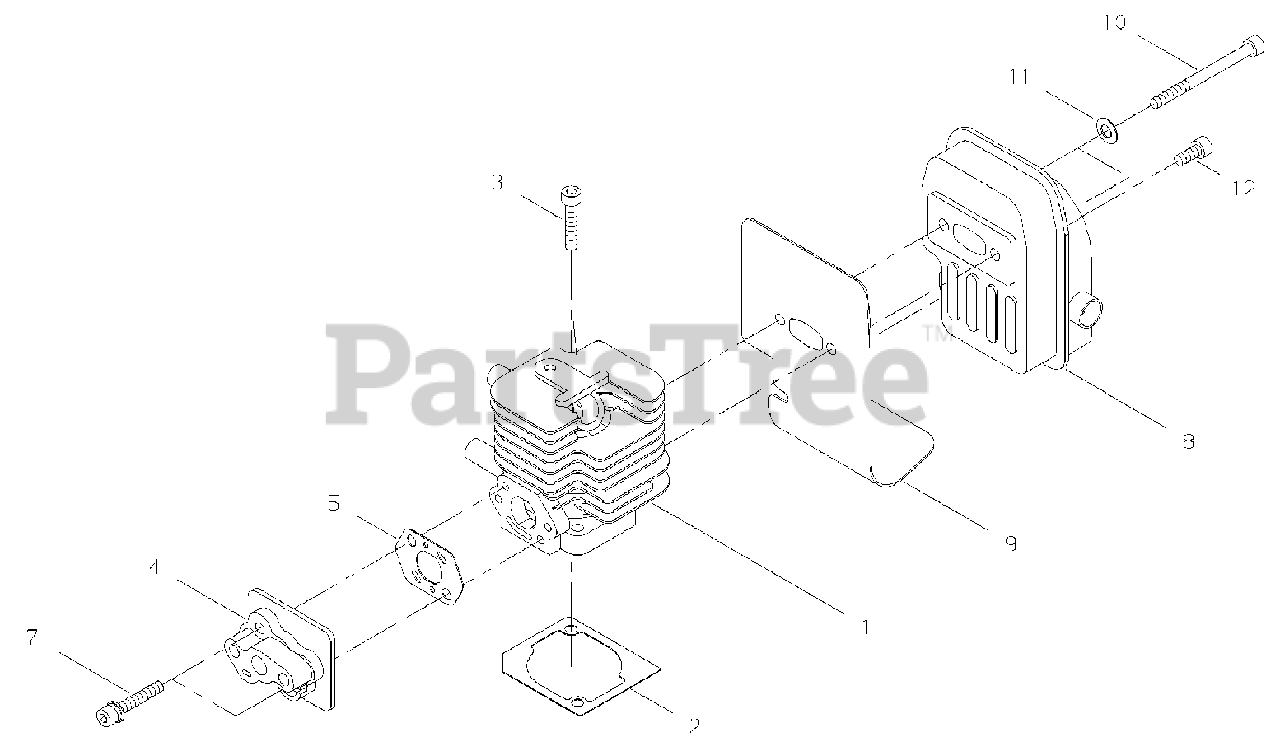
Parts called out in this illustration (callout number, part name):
1-1	CYLINDER
2	GASKET, CYLINDER
3	BOLT 5×25
4	INSULATOR, INTAKE
5	GASKET, INTAKE
7	BOLT M5×30
8	MUFFLER
9	HEAT SHIELD, EXHAUST
10	BOLT M5×50
11	WASHER, FLAT 5.5×10×0.8
12	BOLT 5×12
